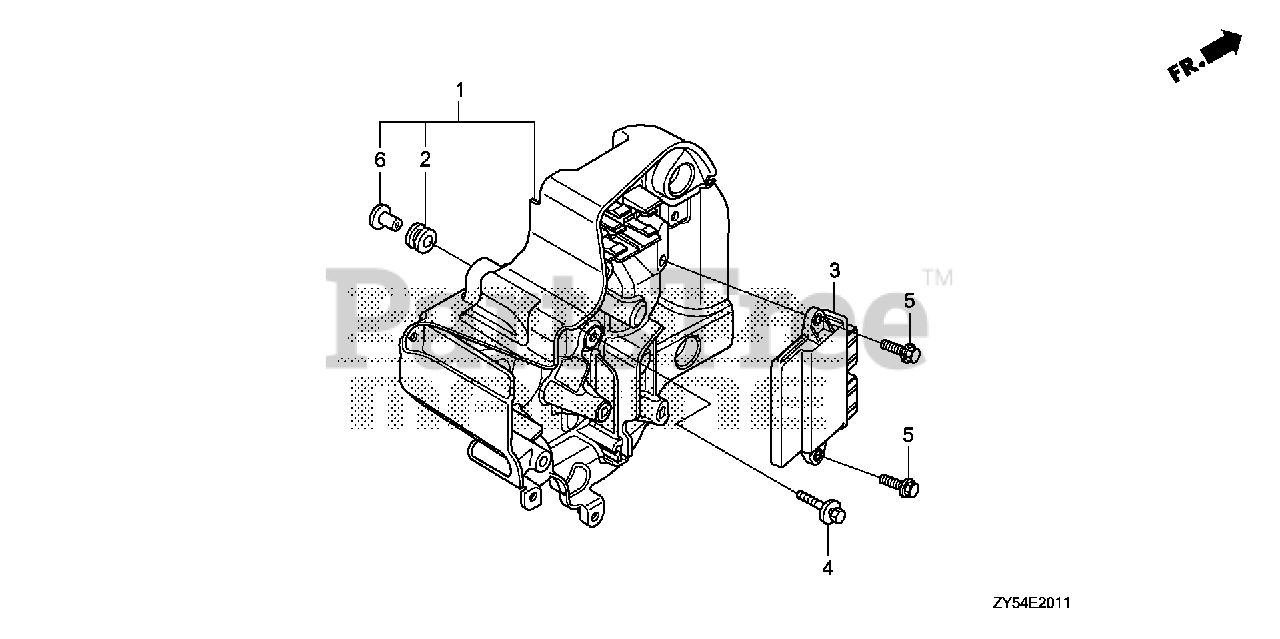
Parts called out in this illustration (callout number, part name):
1	CASE ASSY., ELECTRONIC PARTS
2	GROMMET, ELECTRONIC PARTS CASE
3	CONTROL UNIT, ELECTRONIC
4	BOLT-WASHER (6X27) (CT200)
5	BOLT, FLANGE (6X20)
6	COLLAR, MODULE IGNITION CONTROL CASE (CDI)
